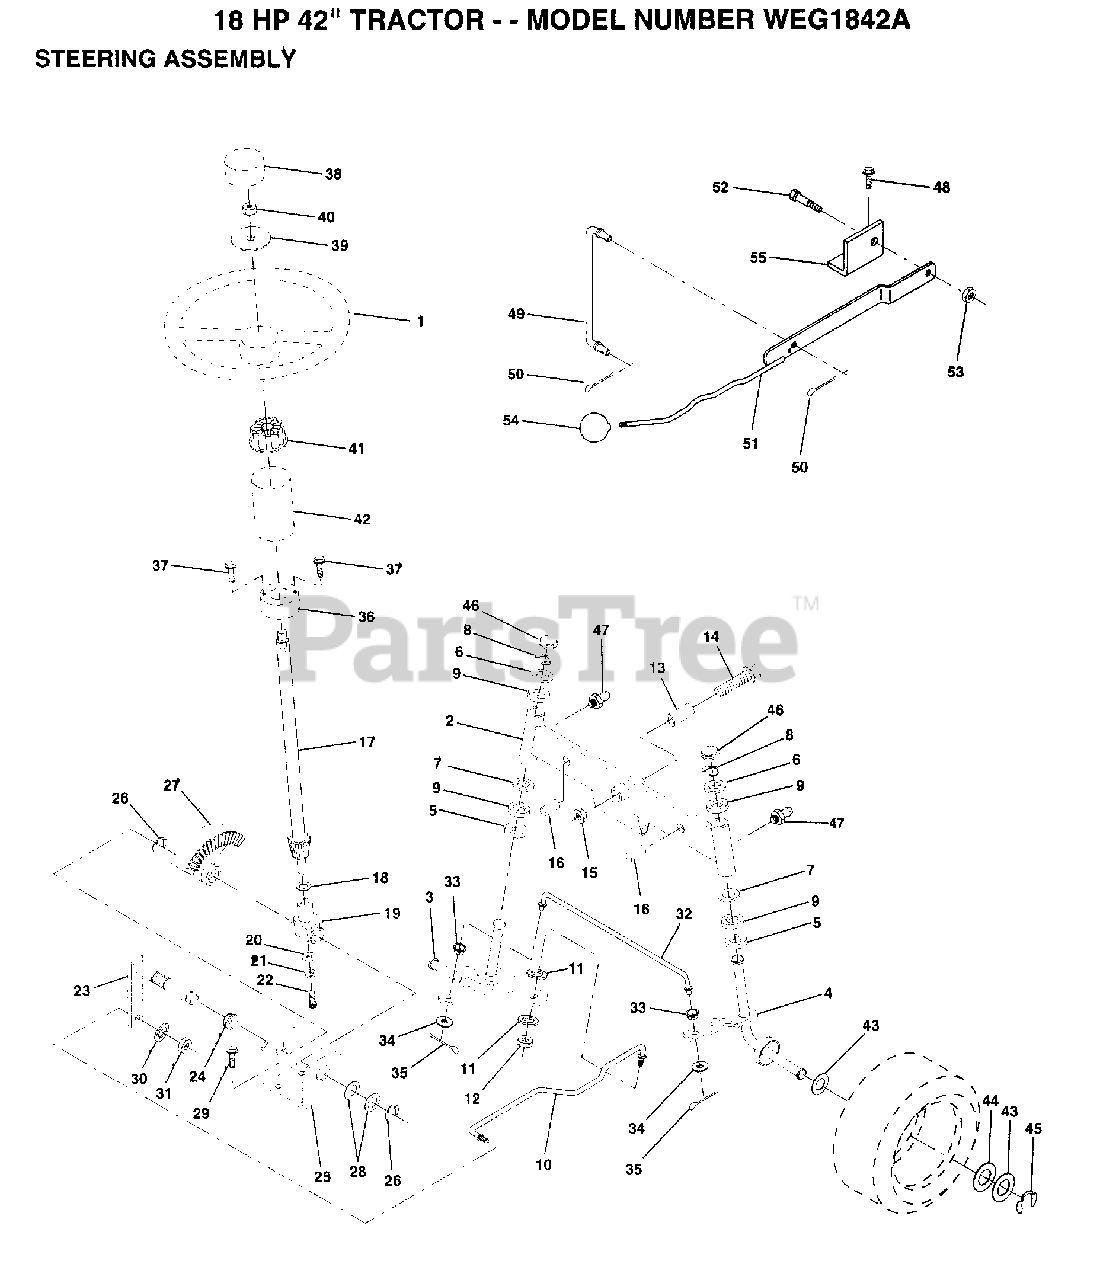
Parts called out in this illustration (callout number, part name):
2	AXLE ASM FRONT
3	SPINDLE LH
4	SPINDLE RH
5	WASHER .T
6	WASHER
7	WASHER
8	RING
9	COL. SRTG. BEAR.
11	LOCKWASHER
13	BEARING
14	BOLT HEX 5/8-11
15	"NUT-LOC,FLANGE LT"
16	AXLE PIN
17	SHAFT&GEAR STR T
18	THRUST WASHER
19	SUPPORT.SHAFT
21	LOCKWASHER
22	"SCREW,SPECIAL"
24	NYLINER T
25	"BRKT,STEERING"
26	RING
27	GEAR SECTOR
28	WASHER .T
29	SCREW
30	LOCKWASHER
32	TIE ROD
33	BUSHING LINK DRAG BLK
34	WASHER
35	COTTER PIN
38	ST WHL INSERT CAP
39	WASHER
41	ADAPTER LT
43	WASHER
44	WASHER
45	RING
46	CAP
47	ZERK M
48	SCREW
49	LINK CLTCH W/NUTS
50	COTTER PIN
52	"BOLT, SHOULDER LT"
54	KNOB T (1/2-HOLE)
55	BRKT.PVT.MAN.LVR.
